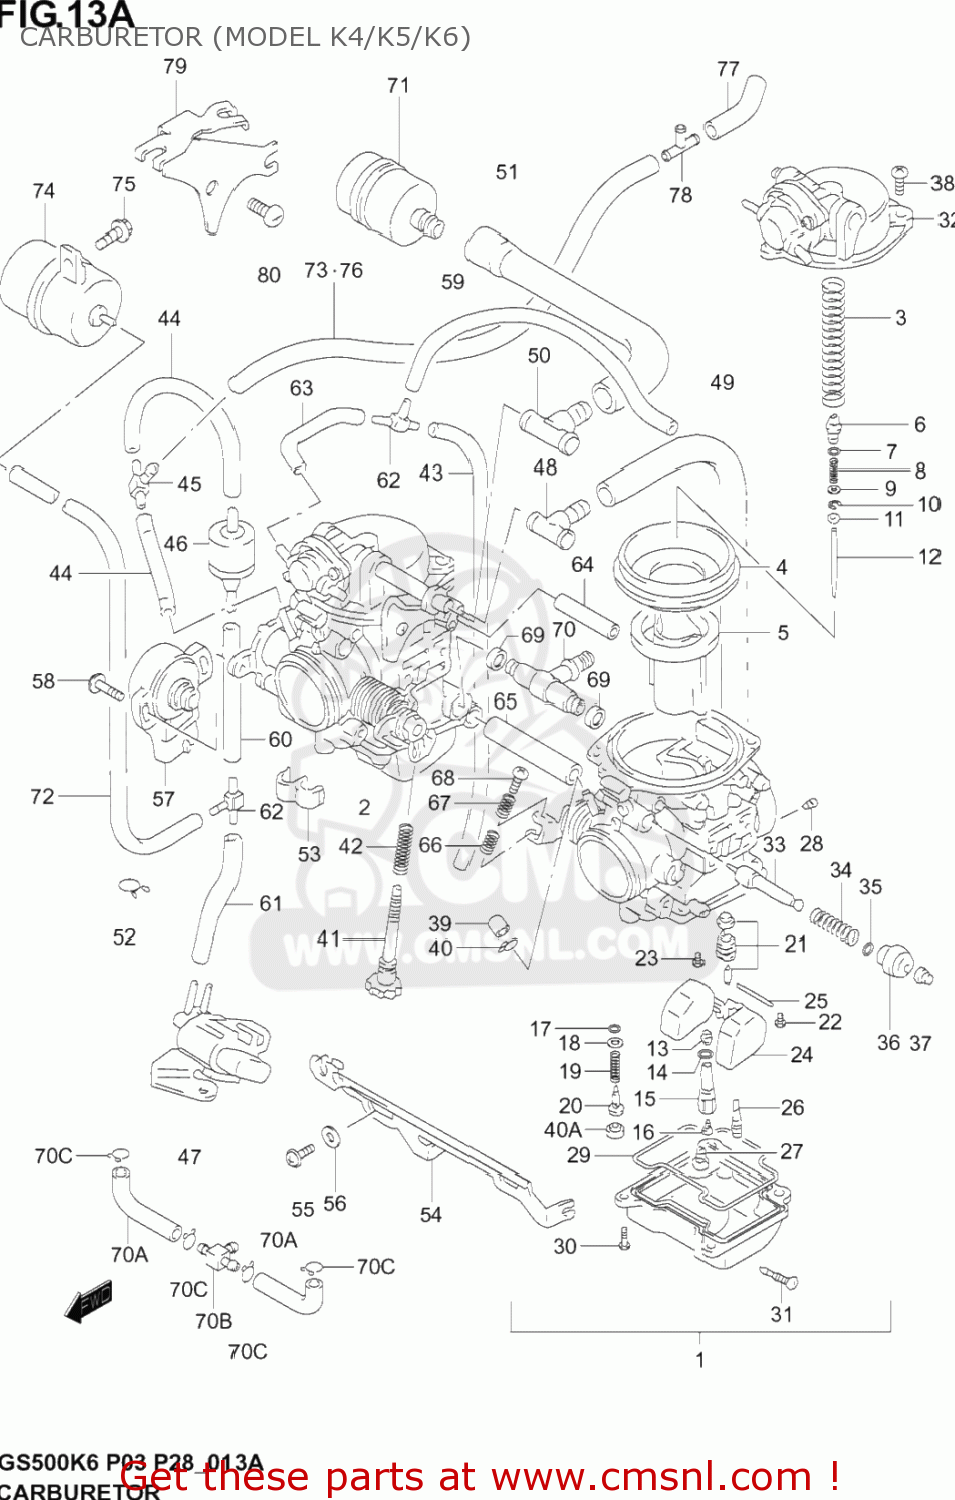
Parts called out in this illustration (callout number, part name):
1	CARBURETOR ASSY, LH
2	CARBURETOR ASSY, RH
3	SPRING
4	DIAPHRAGM
5	VALVE,PISTON
6	HOLDER
7	O RING(D:1.9,ID:4.8)
8	SPRING
9	WASHER
10	E RING,MULTIPLE JET NOZZLE
11	RING
12	NEEDLE, JET (5DH59-1)
13	JET,NEEDLE(P-5M)
14	O RING
15	HOLDER,JET
16	JET,MAIN(130)
17	O RING,PILOT AIR SCREW
18	WASHER
19	SPRING,THROTTLE SCREW
20	ADJUSTER
21	VALVE ASSY,NEEDLE
22	SCREW
23	SCREW
24	FLOAT ASSY
25	PIN,FLOAT
26	JET,PILOT(17.5)
27	JET,MAIN(60)
28	JET,PILOT AIR(170)
29	GASKET (NAS)
30	SCREW
31	SCREW,DRAIN
32	COVER ASSY,DIAPHRAGM,L
33	PLUNGER
34	SPRING
35	O RING
36	GUIDE SCREW,PLUNGER
37	CAP,STARTER VALVE
38	SCREW
39	CAP
40	CLIP
40A	PLUG
41	SCREW,ADJUST
42	SPRING
43	HOSE(3.5X7.5X600)
44	HOSE(3.5X7.5X600)
45	NIPPLE
46	VALVE CHECK AS
47	VALVE ASSY,3WAY SOLENOID
48	HOSE
49	HOSE
50	3 WAY
51	HOSE
52	CLIP
53	CLIP
54	PLATE
55	SCREW
56	PACKING
57	SENSOR ASSY,THROTTLE
58	SCREW,SENSOR
59	HOSE(3.5X7.5X600)
60	HOSE(3.5X7.5X600)
61	HOSE(3.5X7.5X600)
62	3 WAY
63	HOSE(3.5X7.5X600)
64	ROD
65	PIPE
66	SPRING,THROTTLE SCREW
67	SPRING
68	SCREW
69	SEAL
70	NIPPLE
70A	HOSE
70B	NIPPLE
70C	CLIP
71	FILTER,2ND AIR CLEANER
72	HOSE(3.5X7.5X600)
73	HOSE(5X10X600)
74	CHAMBER,VACUUM
75	BOLT
76	HOSE(5X10X600)
77	HOSE(5X10X600)
78	JOINT,3 WAY
79	BRACKET
80	SCREW
